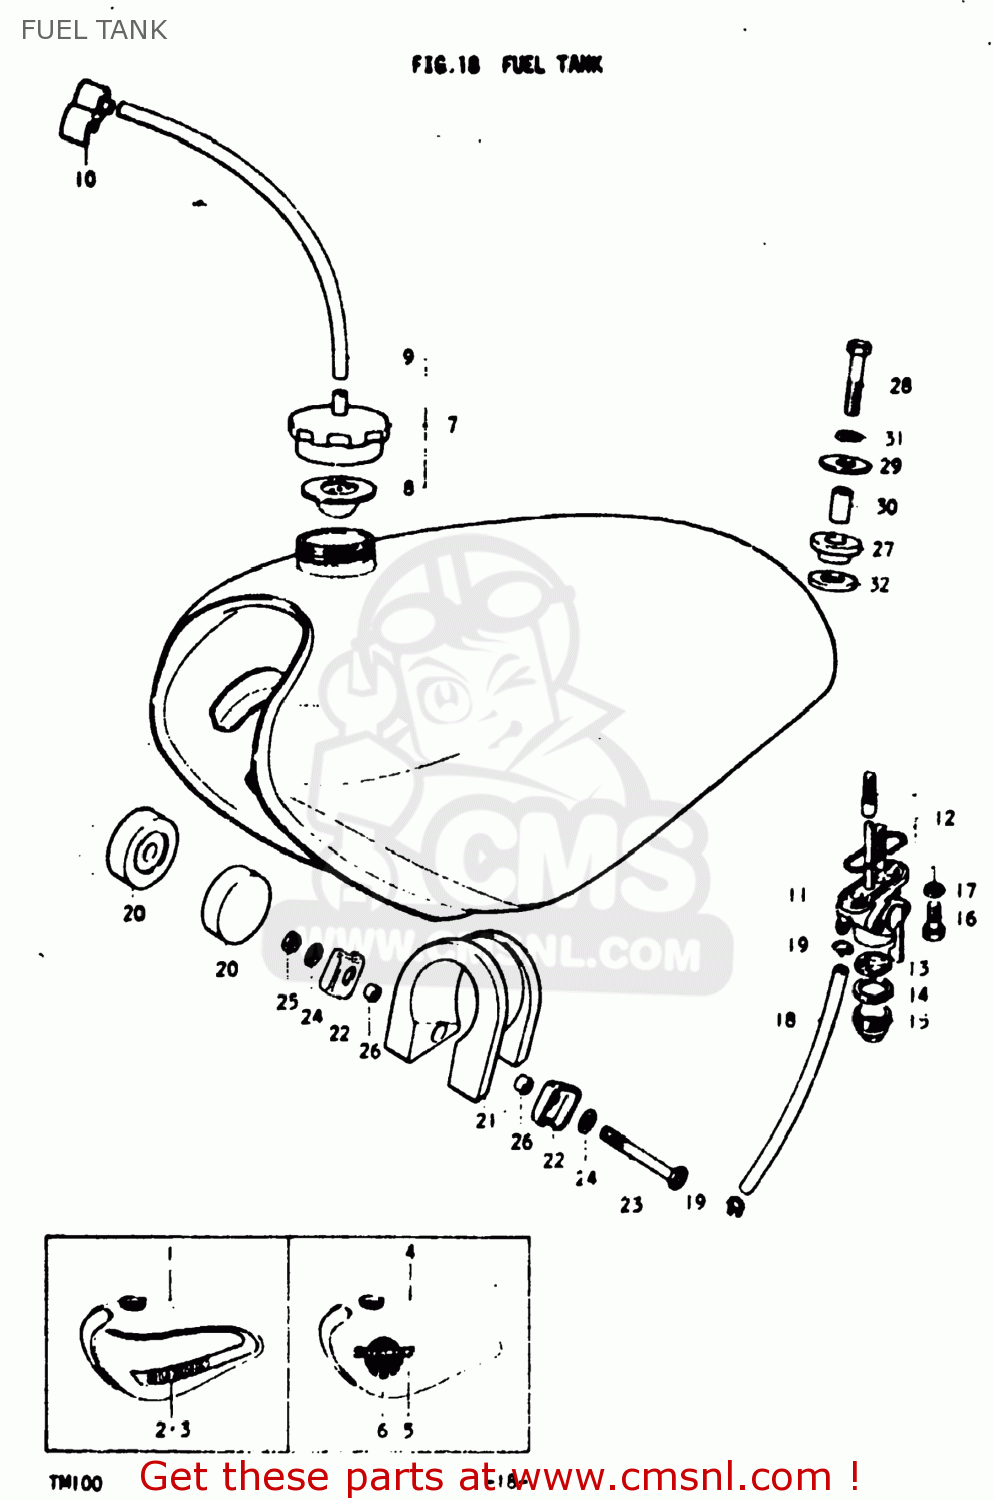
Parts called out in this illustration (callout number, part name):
1	TANK ASSEMBLY,FUEL
2	TAPE,FUEL TANK
3	TAPE,FUEL TANK
4	TANK ASSEMBLY,FUEL
5	EMBLEM
6	TAPE,FUEL TANK
7	CAP ASSY,FUEL TANK FILLER
8	GASKET,FUEL TANK CAP (NAS)
9	HOSE
10	CLAMP,FUEL
11	COCK ASSEMBLY,FUEL
12	COCK ASSEMBLY,FUEL
13	NET,STRAINER
14	GASKET,FILTER (NAS)
15	CUP,FUEL COCK STRAINER
16	SCREW
17	GASKET
18	HOSE
19	CLIP
20	CUSHION
21	CUSHION,FUEL TANK,REAR
22	CLIP
23	BOLT
24	WASHER 6MM
25	NUT
26	SPACER (6.1X8X5.2)
27	CUSHION
28	** SUPERSEEDED
29	WASHER
30	SPACER
31	LOCK WASHER
32	CUSHION
